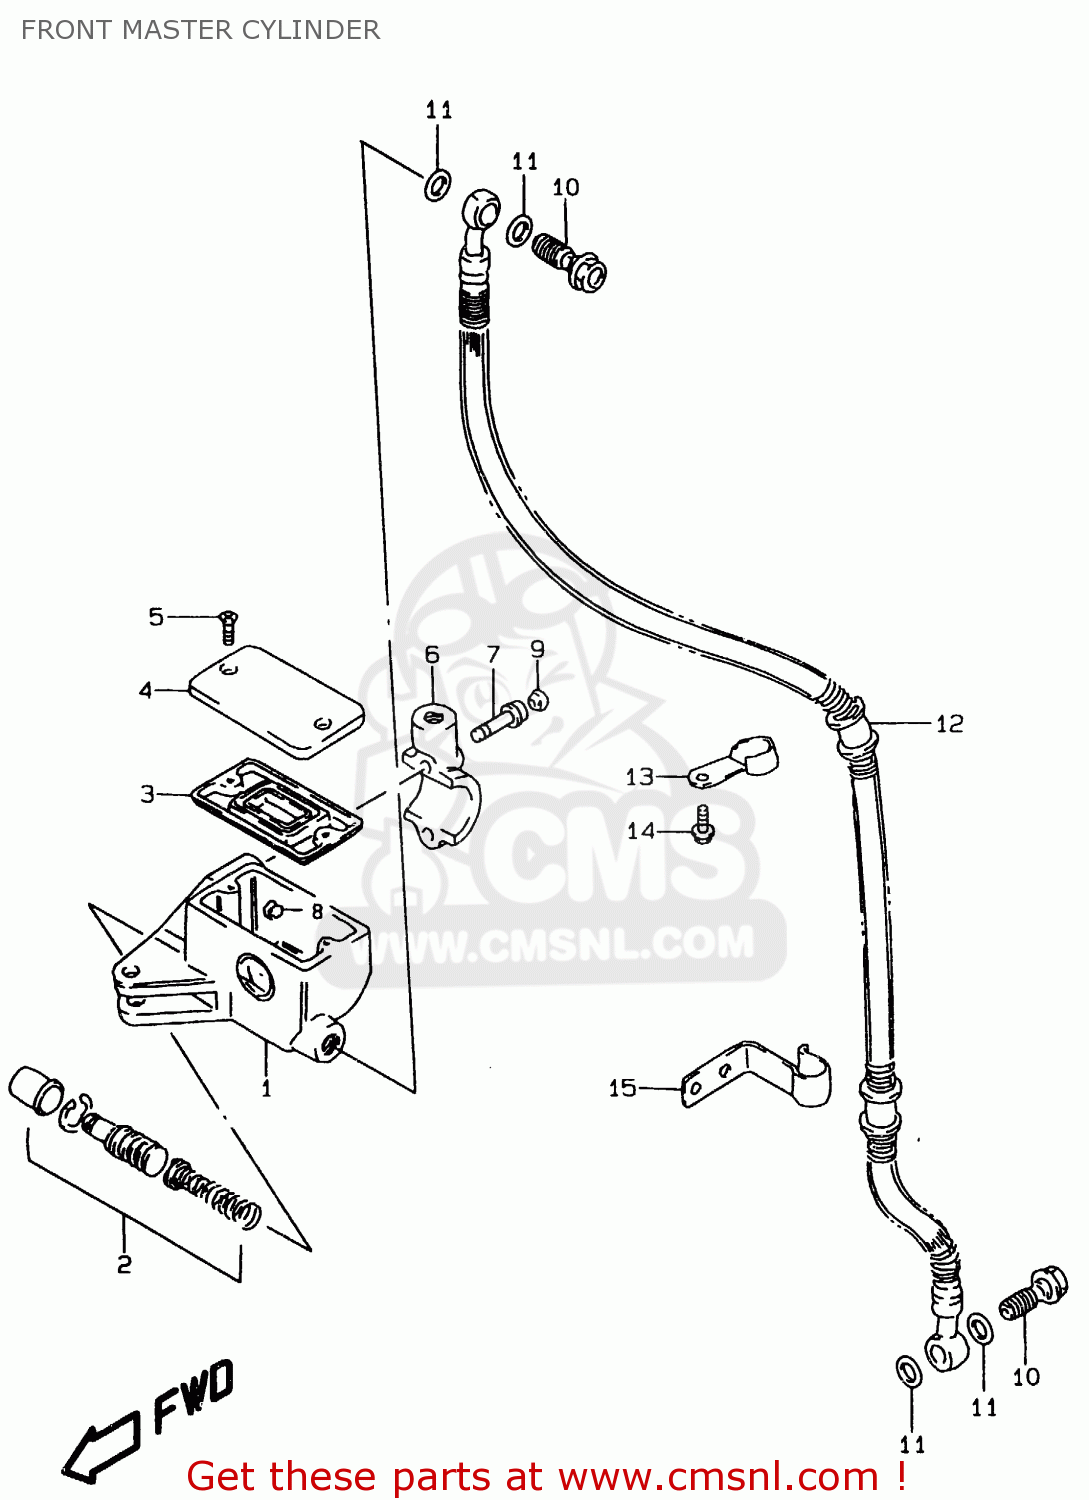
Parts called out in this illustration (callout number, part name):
1	CYLINDER ASSY,FR MASTER
2	PISTON/CUP SET
3	4
4	CAP
5	SCREW
6	HOLDER
7	BOLT
8	PROTECTOR
9	CAP(OD:10)
10	BOLT UNION
11	WASHER(10X15X1.5)
12	HOSE,FR BRAKE
13	GUIDE,BRAKE HOSE NO.1
14	BOLT
15	GUIDE,BRAKE HOSE NO.2
